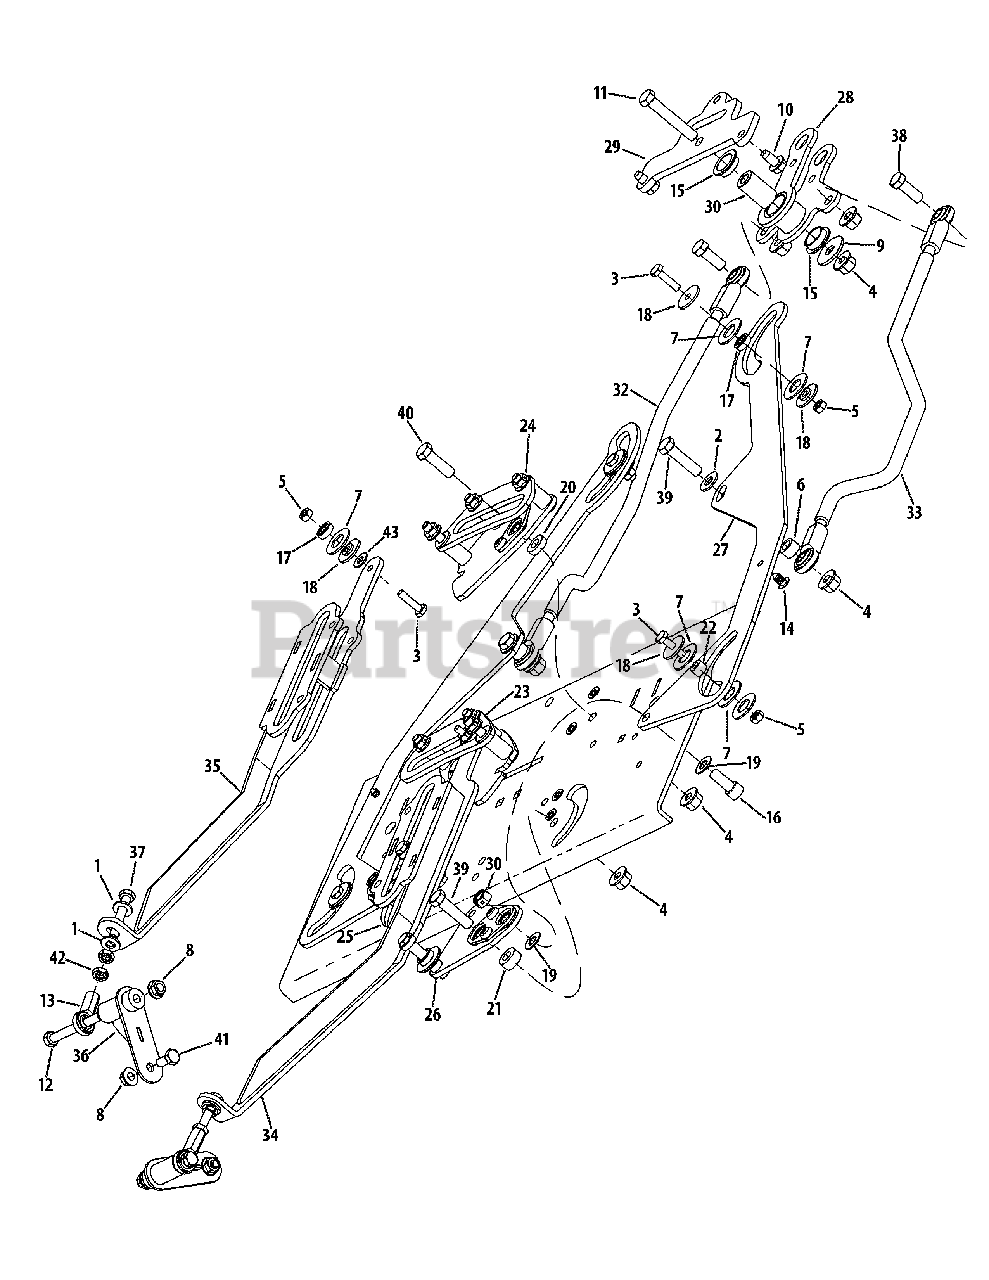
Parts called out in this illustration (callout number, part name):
1	Washer, .344 x .688 x .063
2	Washer, .406 x .813 x .063
3	Hex Screw, 1/4-20 x 1.00
4	Flange Counter Lock Nut, 3/8-16
5	Counter Lock Nut, 1/4-20
6	Spacer, .407 x .625 x .375
7	Washer, .550 x 1.25 x .068
8	Flange Counter Lock Nut, 5/16-18
9	Washer, .411 x 1.25 x 1.00
10	Flange Screw, 5/16-18 x .625
11	Hex Screw, 3/8-16 x 2.25
12	Hex Screw, 5/16-18 x 2.75
13	Rod End, 5/16
14	Rivet, 1/4 x .625
15	Flange Bearing, .752 x 1.25 x .305
16	Socket Head Screw, 3/8-16 x .88
17	Ball Bearing, .25 x .625 x .196
18	Shoulder Spacer, .251 x 1.00 x .06
19	Spacer, .381 x .750 x .040
20	Spacer, .381 x .75 x .150
21	Spacer, .381 x .750 x .312
22	Spacer, .256 x .500 x .330
23	LH Speed Control Cam Assembly
24	RH Speed Control Cam Assembly
25	LH Steering Pivot Assembly
26	RH Steering Pivot Assembly
27	Control Link Plate
28	Front Steering Pivot Assembly
29	Steering Pivot Mount Plate
30	Spacer, .385 x .750 x 1.28
31	Flat Washer, .25 x .630 x .0515
32	LH Control Rod Assembly
33	RH Control Rod Assembly
34	Pump Control Arm Assembly
35	RH Pump Control Arm Assembly
36	Pump Control Spacer Assembly
37	Hex Screw, 5/16-24 x 2.00
38	Hex Screw, 3/8-16 x 1.00
39	Hex Screw, 3/8-16 x 1.50
40	Hex Screw, 3/8-16 x 1.25
41	Hex Screw, 5/16-18 x .625
42	Jam Nut, 5/16-24
